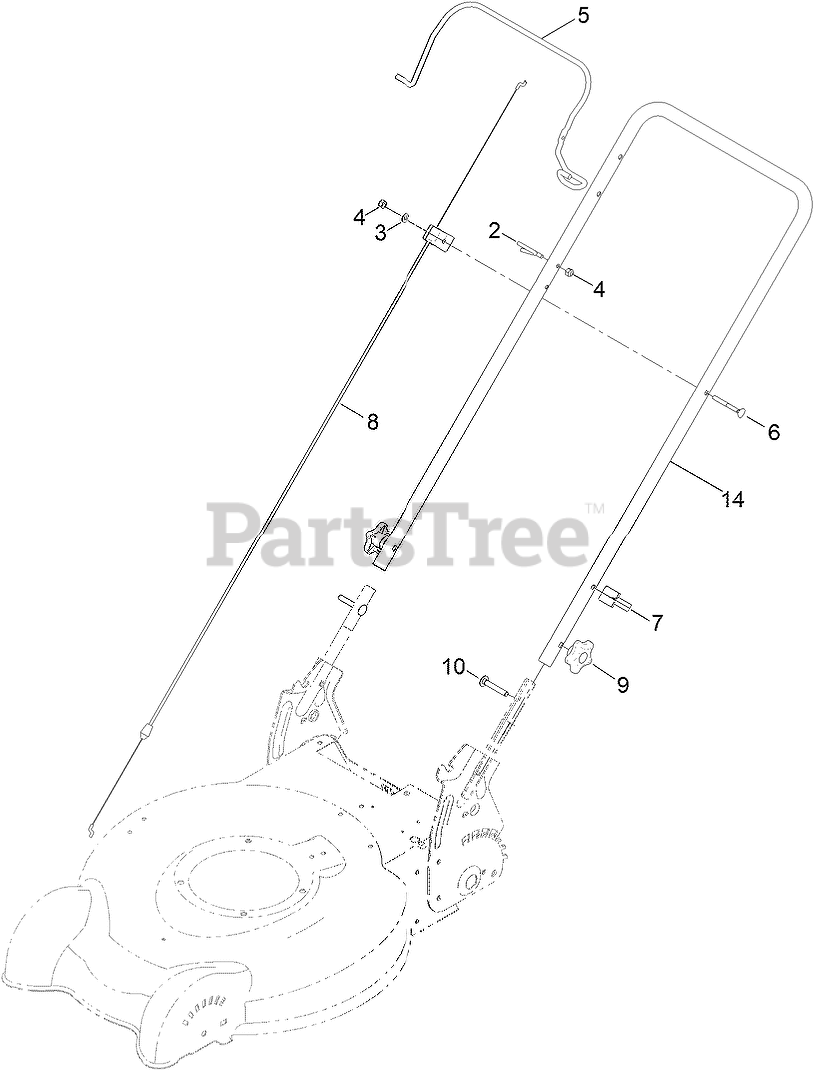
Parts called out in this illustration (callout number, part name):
2	GUIDE-ROPE
3	WASHER-FLAT
4	NUT-LOCK, NI
5	BAIL-BRAKE
6	SCREW-HANDLE
7	GUIDE-CABLE
8	CABLE-BRAKE, ENGINE
9	KNOB-HANDLE
10	Screw-CARR
